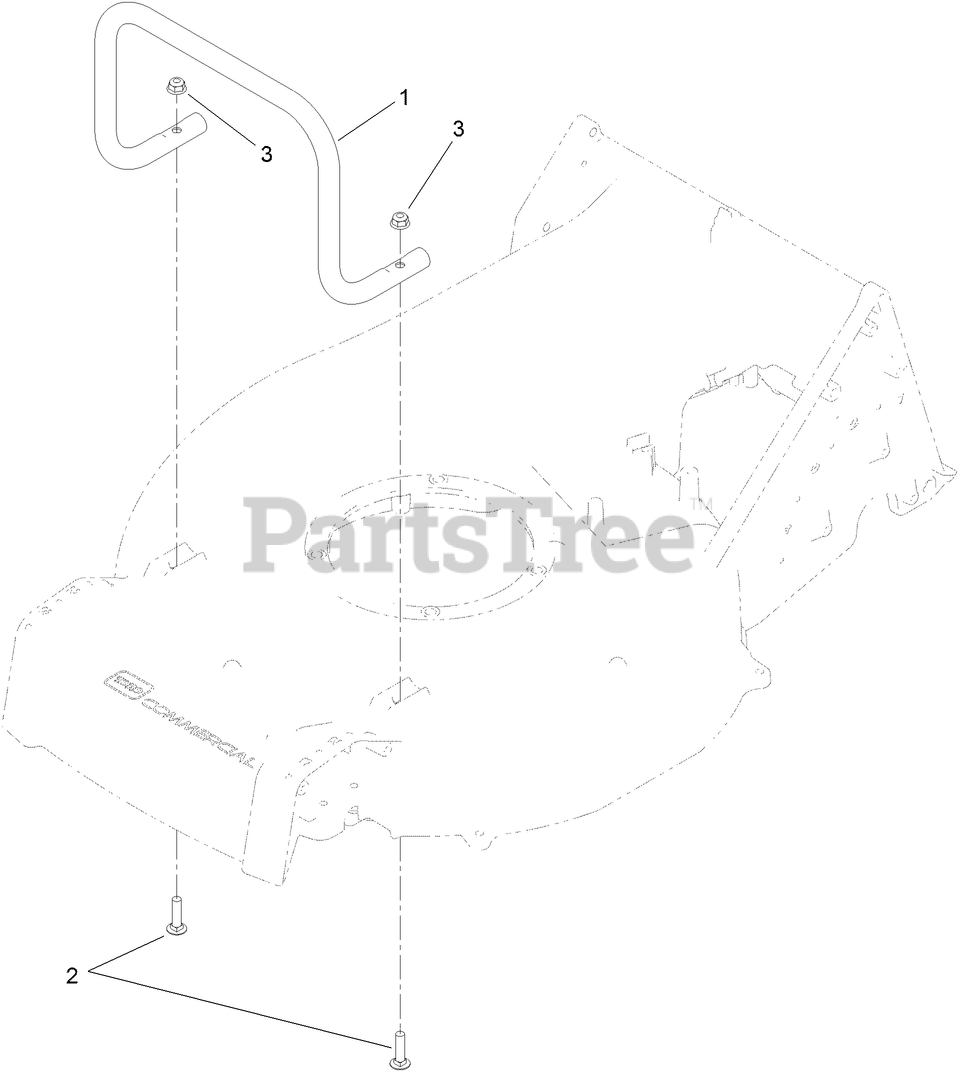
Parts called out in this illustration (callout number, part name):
1	GUARD-ENGINE
2	SCREW-CARR
3	NUT-HF, NI
